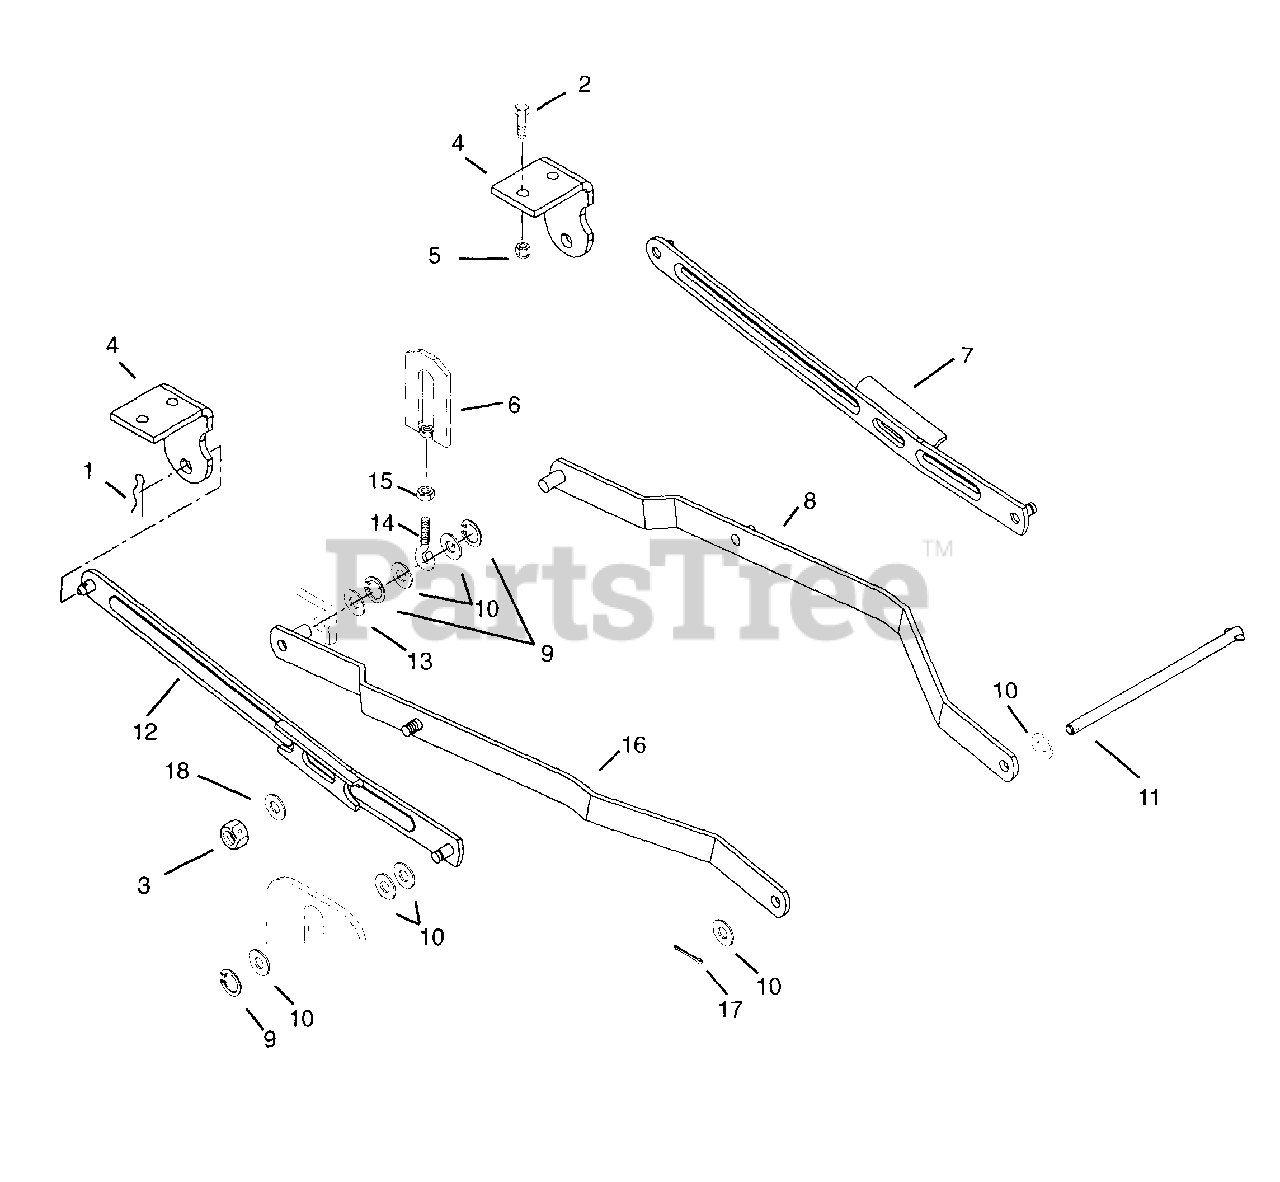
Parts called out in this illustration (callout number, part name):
1	PIN-HAIR-EXT .12X.31X2.37 YWZC
2	@BLT-HEX .38-16X.75 GR5 YWZC
3	@NUT-LK-CTR .62-11 YWZC
4	REAR HANGER
5	NUT-LK-CTR .375-16 YWZC
6	LINK, ADJUSTMENT
7	REAR HANGER, L.H.
8	L.H. LIFT ARM
9	RG-RTNG-EXT .500X.050 (SNAP)
10	@WSHR-FL-STL.656X1.31X.095 YWZ
12	REAR HANGER, R.H.
13	@WSHR-FL-STL.531X1.06X.095YWZC
14	HANGER YWZC
15	NUT-HEX-JAM .375-16 YWZC
16	R.H. LIFT ARM
17	@PIN-CTR .12X1.00 EXTPRSQCT YZ
18	@WSHR-FL-STL.656X1.31X.095 YWZ
